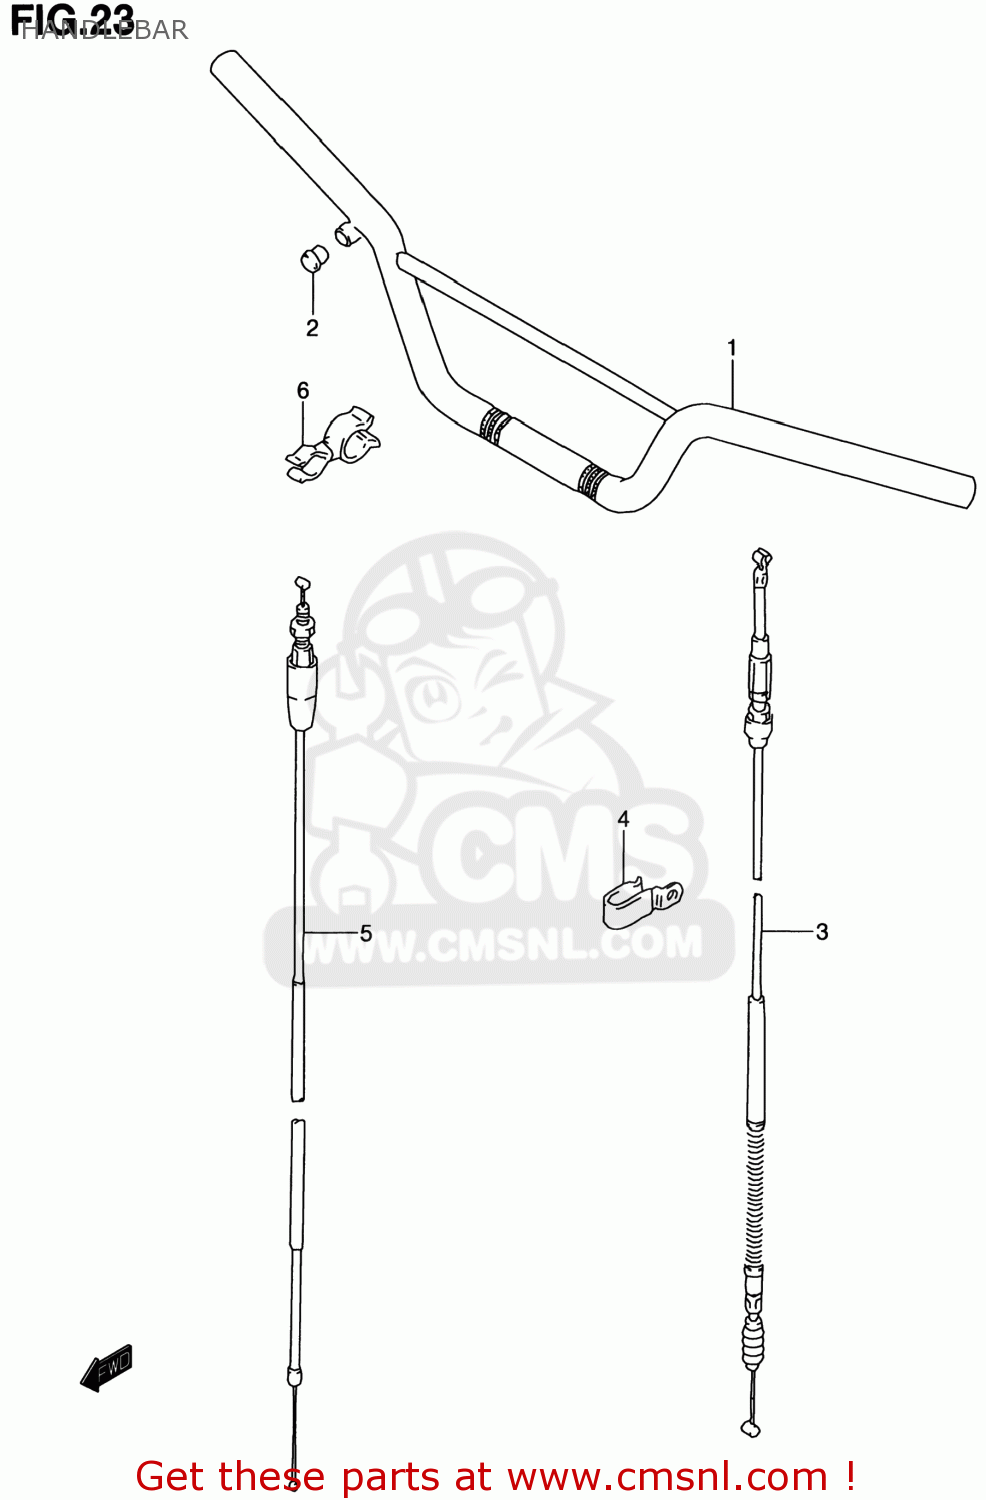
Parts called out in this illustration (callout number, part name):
1	HANDLEBAR COMP
2	CAP(OD:14)
3	CABLE ASSY,CLUTCH
4	CLAMP
5	CABLE ASSY,THROTTLE
6	CLAMP
